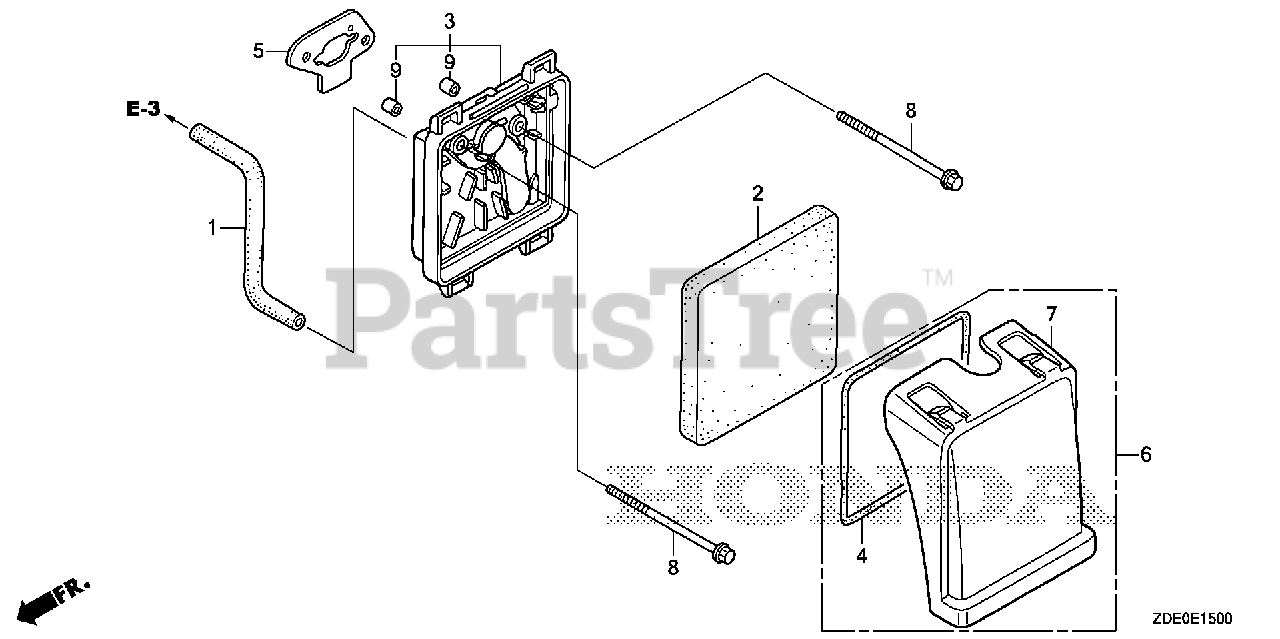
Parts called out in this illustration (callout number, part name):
1	TUBE, BREATHER
2	ELEMENT, AIR CLEANER
3	HOUSING, AIR CLEANER
4	SEAL, AIR CLEANER
5	GASKET, AIR CLEANER
6	COVER, AIR CLEANER
7	COVER, AIR CLEANER
8	BOLT, FLANGE (5X65)
9	COLLAR, AIR CLEANER
